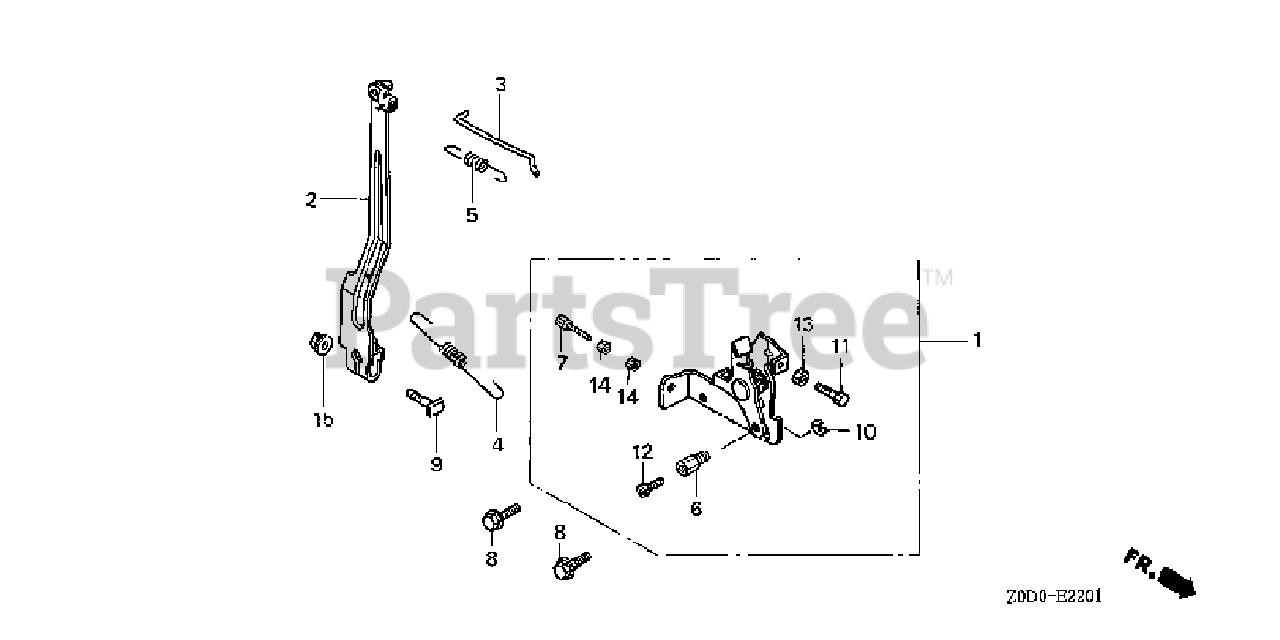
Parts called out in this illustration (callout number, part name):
1	CONTROL ASSY.
2	SPRING, GOVERNOR
3	ROD, GOVERNOR
4	SPRING, GOVERNOR
5	SPRING, THROTTLE RETURN
6	HOLDER, WIRE
7	BOLT, CABLE ADJUSTING (6X34)
8	BOLT, FLANGE (6X14)
9	BOLT, GOVERNOR ARM
10	CIRCLIP (5MM)
11	BOLT, HEX. (5X20)
12	SCREW, PAN (4X6)
13	NUT, HEX. (5MM)
14	NUT, HEX. (6MM)
15	NUT, FLANGE (6MM)
